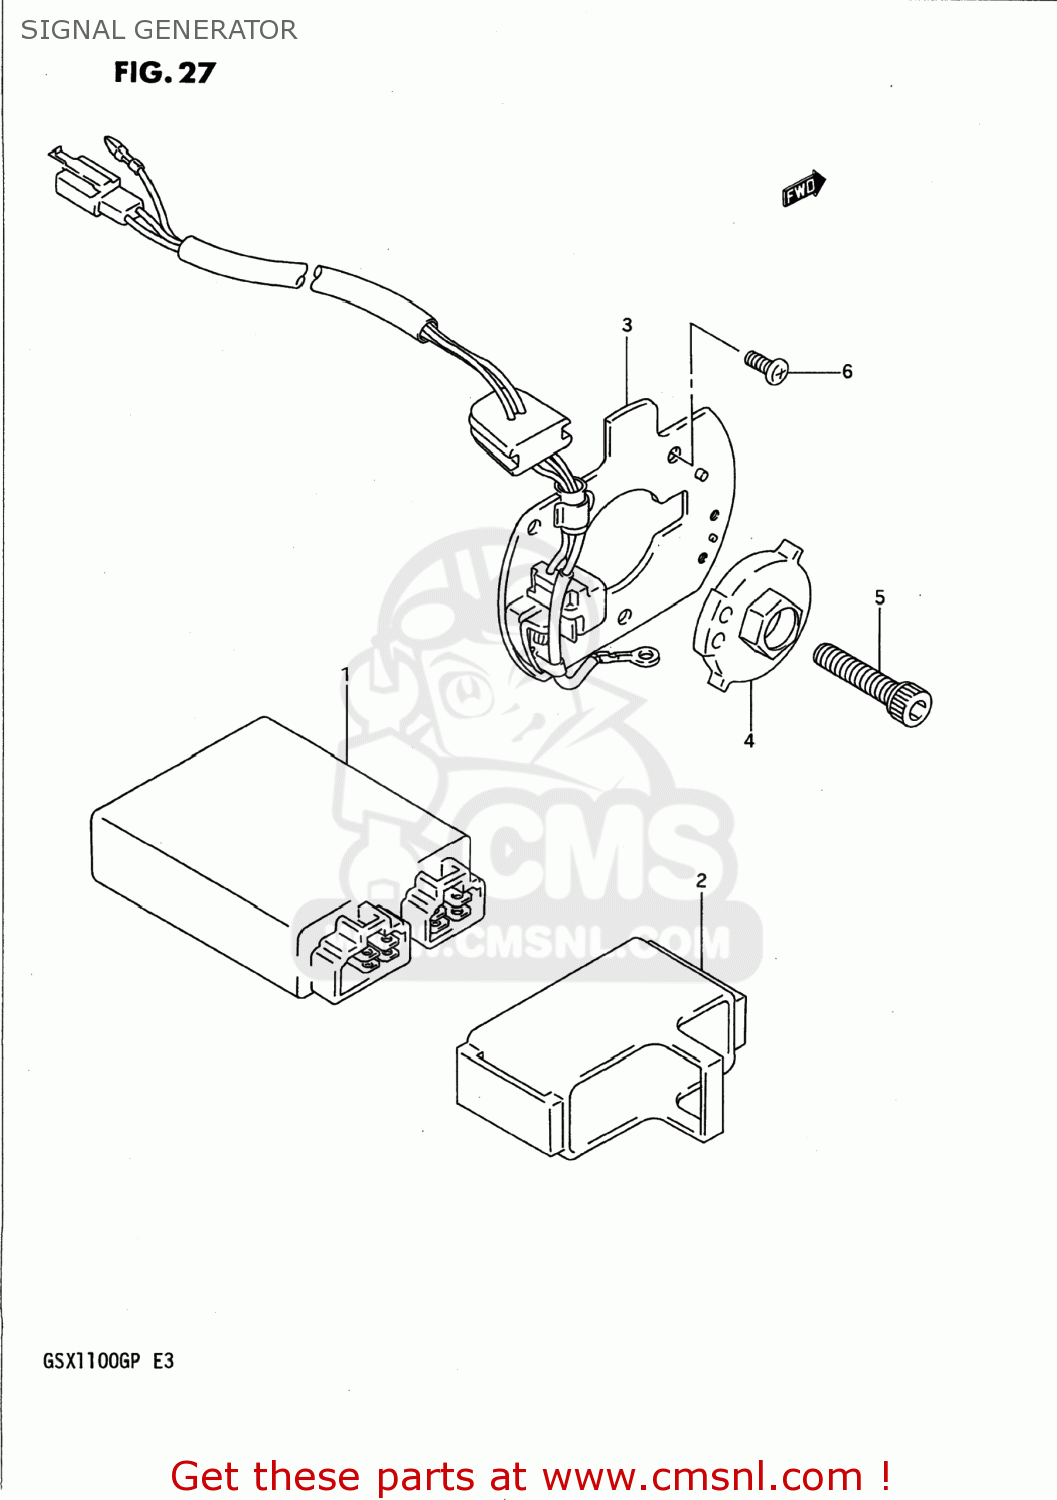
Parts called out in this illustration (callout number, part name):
1	IGNITER ASSEMBLY
2	CUSHION,IGNITER
3	GENERATOR ASSEMBLY,SIGNAL
4	ROTOR,SIGNAL
5	BOLT
6	SCREW
